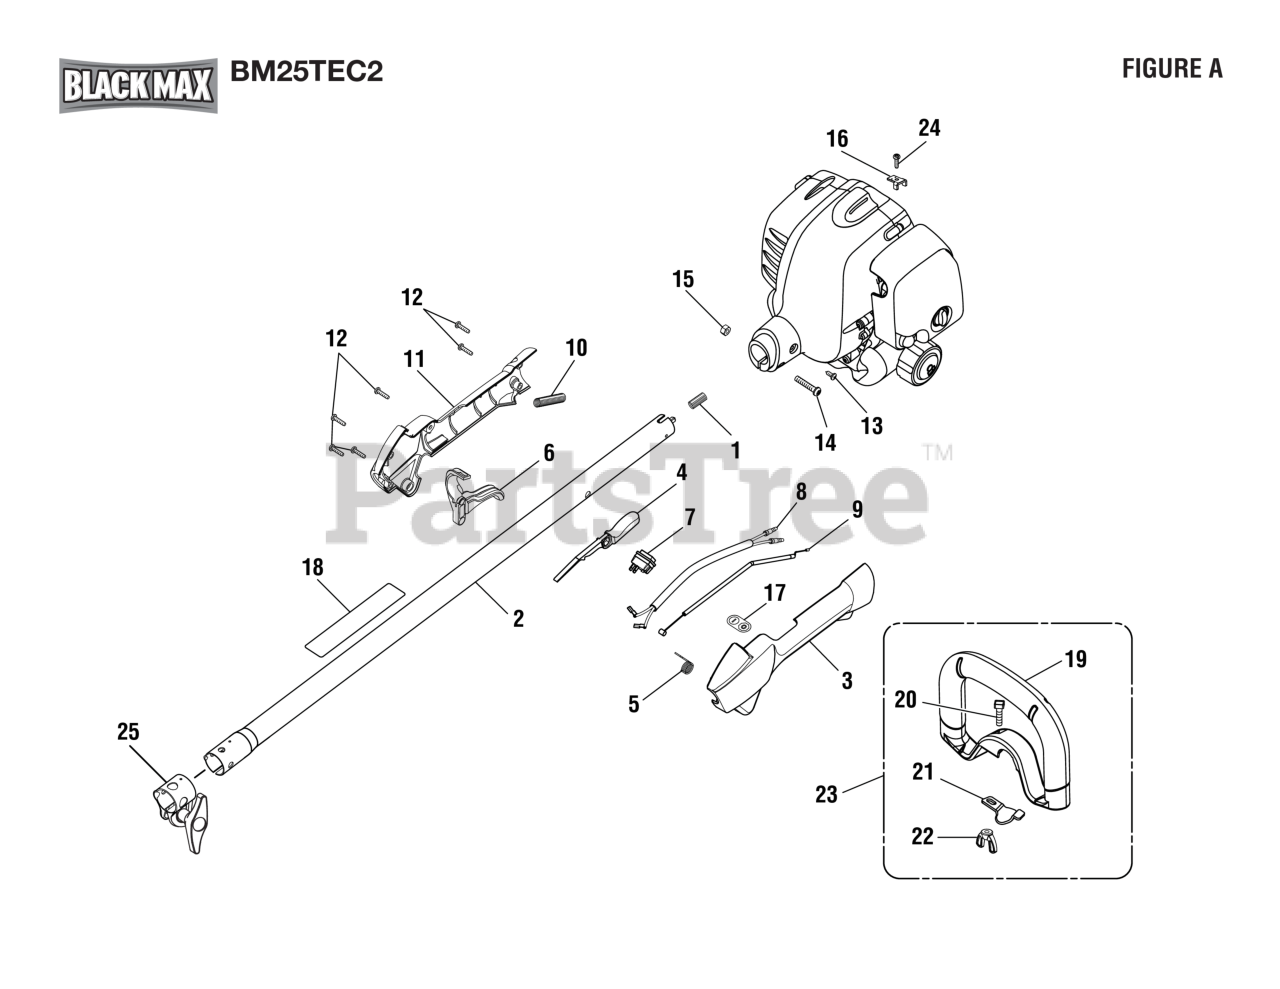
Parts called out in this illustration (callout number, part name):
1	COMPRESSION SPRING
2	Upper Shaft Assembly
3	REAR HANDLE SUPPORT
4	Trigger Lock
5	Torsion Spring (Throttle Trigger)
7	On/Stop Switch
8	Lead Assembly
9	CABLE, THROTTLE
10	Corrugated Tube (225 mm)
11	REAR HANDLE COVER
12	Screw (M4 x 20 mm, T20 Torx Pan Hd. S.T.)
13	Screw (#8-16 x 1/2 in., Tri-Lobular)
14	Screw (M6 x 30 mm, T27 Torx Button Hd.)
15	Hex Nut (M6.3 x 1)
16	THROTTLE CABLE CLAMP
17	On/Stop Label
18	Warning Icon Label
19	Front Handle w/Grip
20	Bolt (1/4-20 x 1 in., Square Hd.)
21	Front Handle Clamp
22	Wing Nut (1/4-20, Plastic)
23	Front Handle Assembly
24	Screw (M4 x 16 mm, T20 Torx Pan Hd. S.T.)
25	Boom Clamp Assembly
